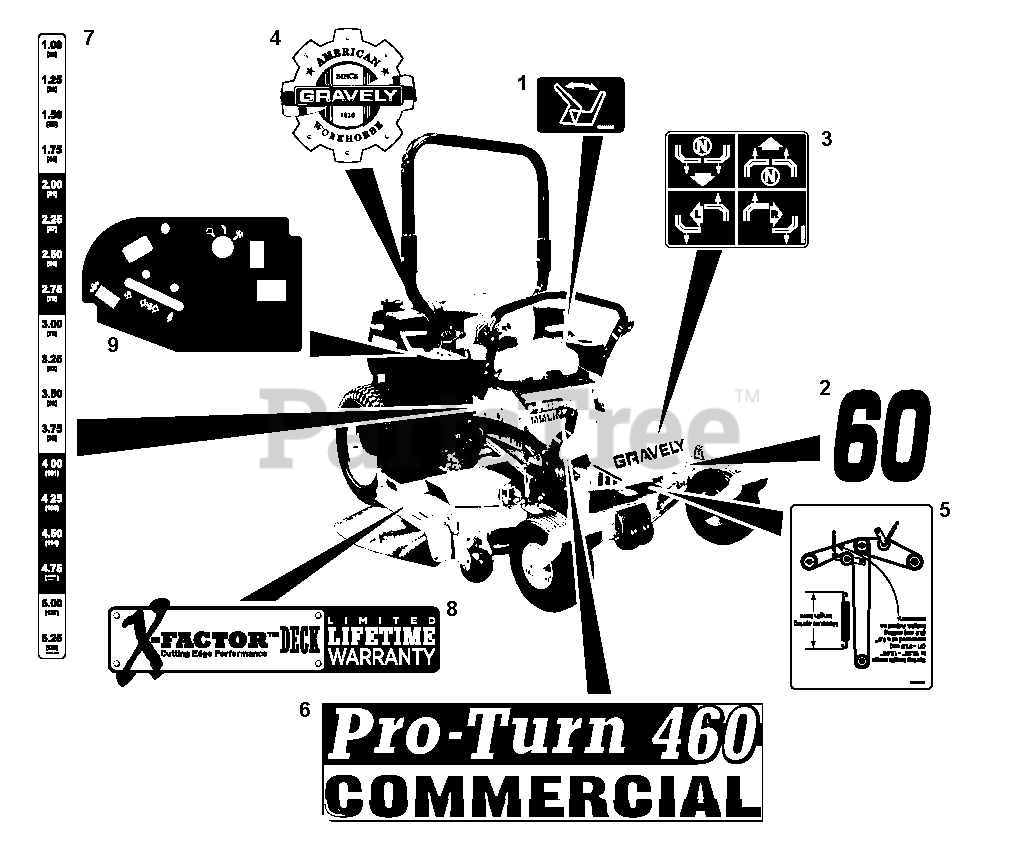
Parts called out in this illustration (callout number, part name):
1	Decal, Seat Release
2	Decal, 52 (992230, 231)
3	Decal, Instructional Steering
4	Decal, Gravely Heritage
5	Decal, Belt Routing (992230, 231, 232, 233, 234, 235, 207)
6	Decal, Pro-Turn 452 (992230, 231)
7	Decal, PT-400 Height of Cut
8	Decal, X-Factor Deck
9	Decal, Control Panel (992230, 232, 234, 235, 239, 207)
